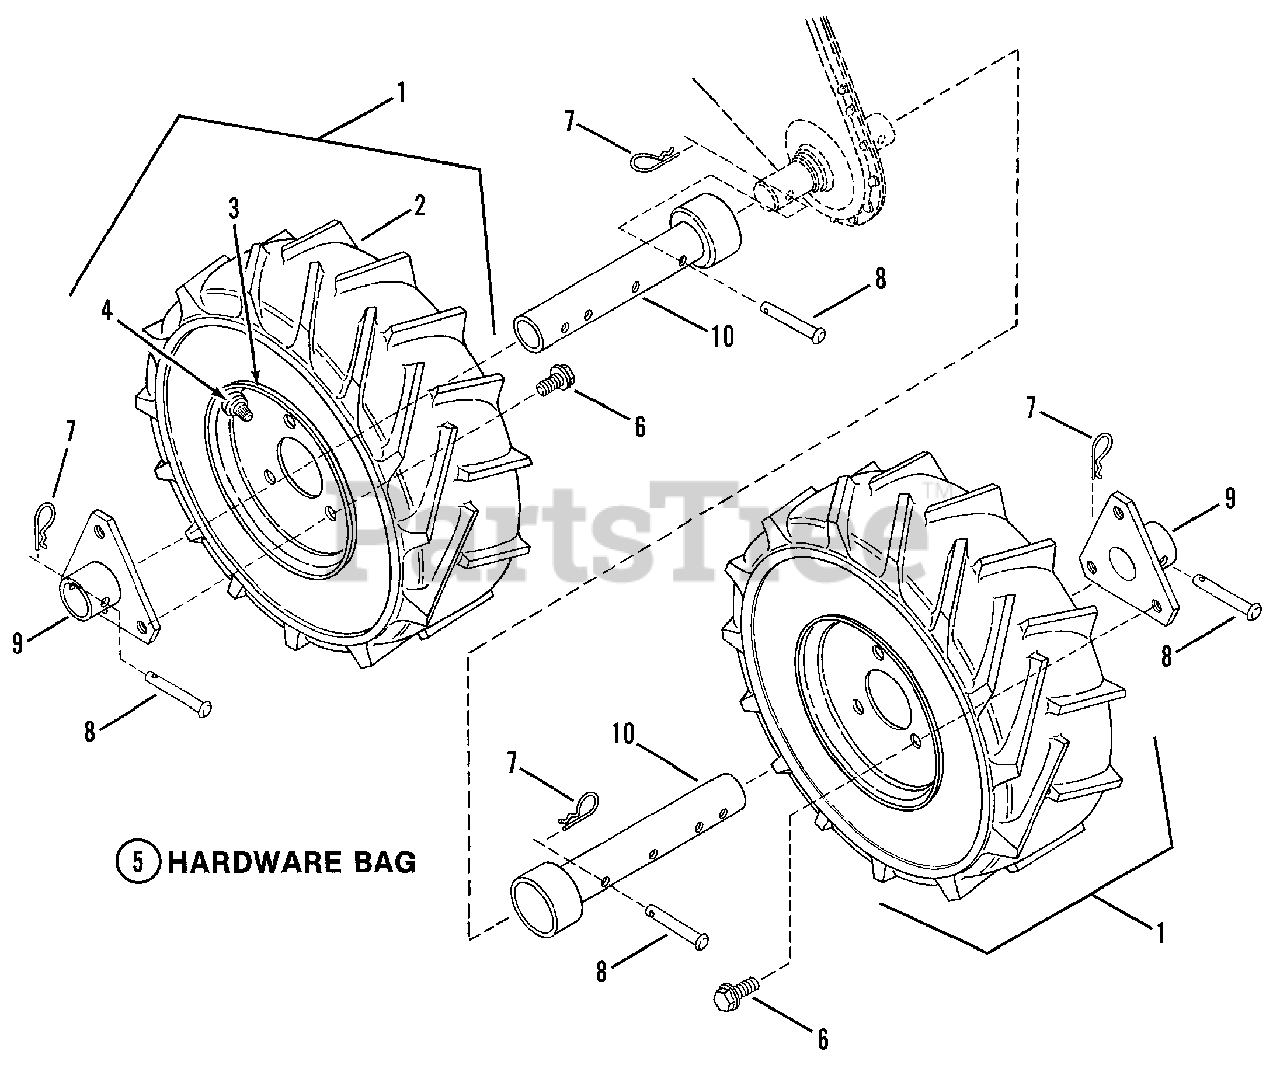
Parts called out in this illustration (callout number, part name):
1	WHEEL ASSM'Y. 16x4.80x8
2	(NLA) TIRE,16x4.80x8 (Lug)
3	RIM
4	VALVE, Air (Snap-in)
5	(NLA) HARDWARE BAG 60272
6	SCREW, 1/2-20x3/4" Hex Head Cap
7	PIN, Hair
8	PIN, Clevis, 3/8x2-1/4"
9	(NLA) HUB, Wheel Structure
10	(NLA) HUB, Adjustable
